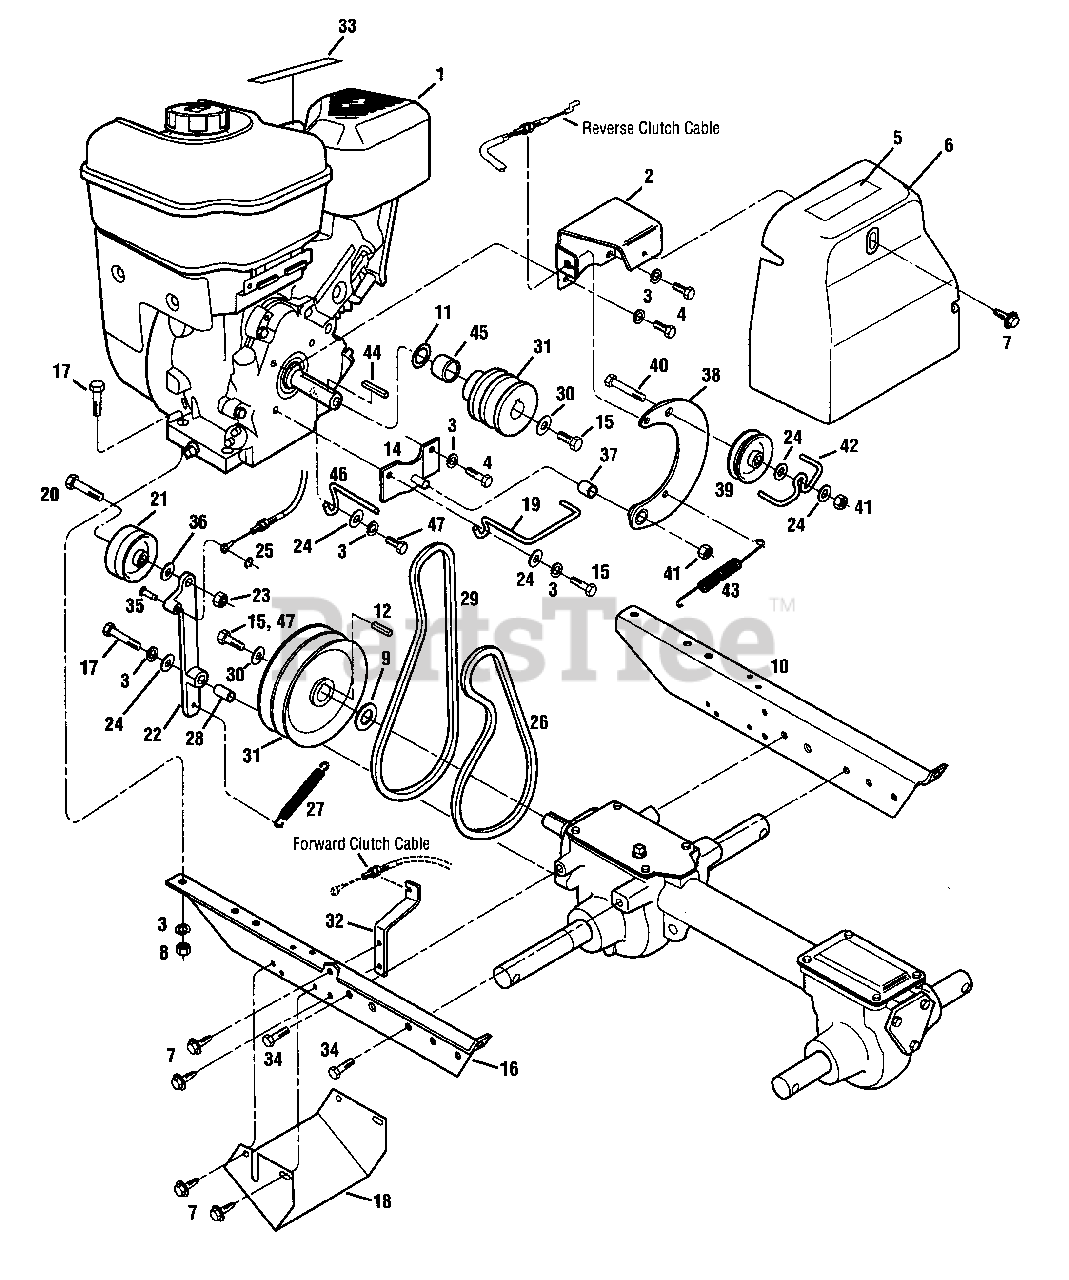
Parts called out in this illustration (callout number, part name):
1	Engine, Recoil Start
2	Bracket, Belt Cover
3	Lockwasher, 5/16
4	Hex Hd. Screw, 5/16-24 x 1/2
5	Decal, Hot Surfaces Warning
6	Belt Cover
7	Flange Screw, Self-Tapping, 1/4-20 x 1/2
8	Hex Nut, 5/16-18
9	Support Washer
10	Engine Bracket, Right
11	Shim
12	Key, 3/16" x 1"
14	Reverse Idler Bracket
15	Hex Screw, 5/16-24 x 1
16	Engine Bracket, Left
17	Hex Screw, 5/16-18 x 1-1/2
18	Guard, Belts/Pulleys
19	Forward Belt Guide
20	Hex Screw, 3/8-16 x 1-1/2
21	Forward Idler Pulley
22	Forward Idler Lever
23	Locknut, 3/8-16
24	Flat Washer
25	Klip Ring
26	Forward Drive Belt
27	Forward Return Spring
28	Bushing, Forward Idler Lever
29	Reverse Drive Belt
30	Belleville Washer
31	Transmission Pulley
32	Bracket, Cable Mounting
33	Decal, Stabilization
34	Hex Screw, 5/16-18 x 5/8
35	Clevis Pin
36	Flat Washer, 3/8
37	Bushing
38	Reverse Idler Arm
39	Pulley, Reverse Idler
40	Hex Screw, 5/16-18 x 2
41	Locknut, 5/16-18
42	Belt Guide
43	Reverse Return Spring
44	Key, 3/16 x 1-1/2
